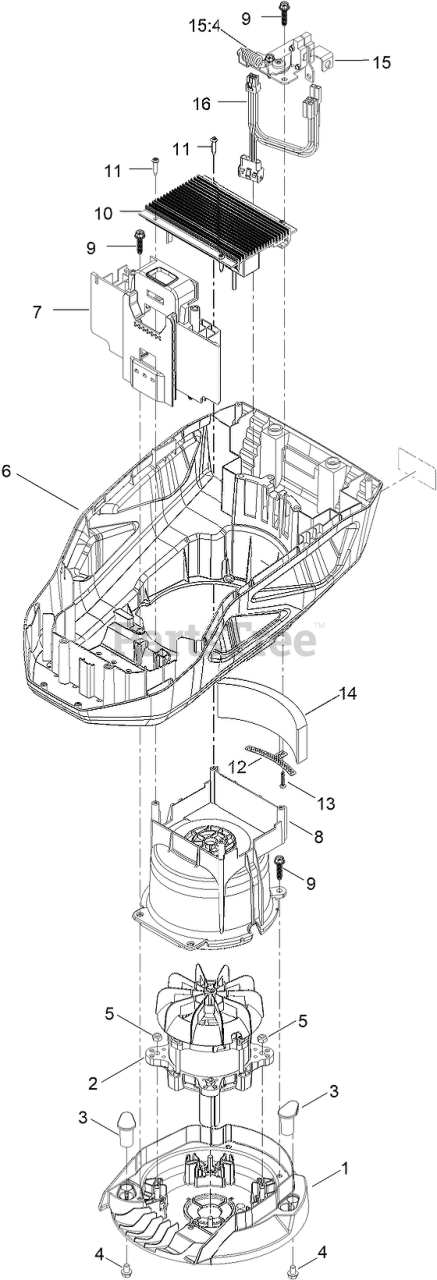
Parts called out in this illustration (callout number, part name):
1	BASE-MOUNT, MOTOR
2	MOTOR-2KW
3	INSERT-MOUNT, Motor
5	NUT-LOCK
6	SHROUD-LOWER
7	MOUNT-BATTERY
8	SHROUD-MOTOR
9	SCREW-FLANGE, PLASTIC
10	CONTROLLER-MOTER [LED]
12	BRACKET-FOAM
13	SCREW-PLASTIC, PPH
15	BAIL SWITCH ASM
15:4	SPRING-EXTENSION
16	HARNESS-WIRE
